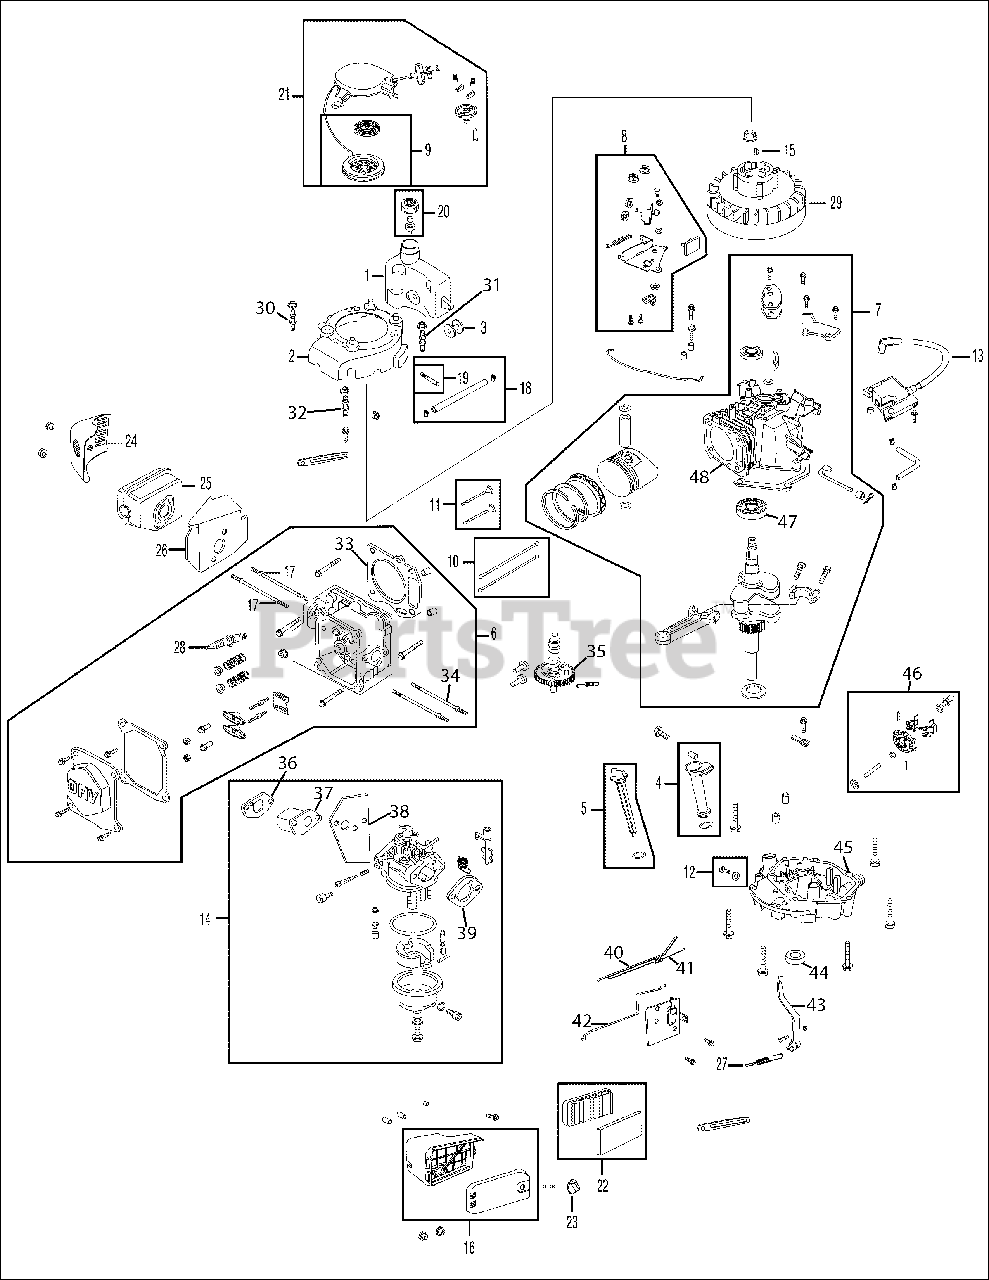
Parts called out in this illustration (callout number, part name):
1	Fuel Tank
2	Flywheel Shroud
3	Rubber Fuel Tank Mounting Washer
4	Oil Filler Tube Assembly
5	Dipstick Assembly
6	Cylinder Head Complete
7	Short Block Assembly
8	Stop Switch and Brake Assembly
9	Recoil Spring and Pulley Assembly
10	Push Rod Kit
11	Valve Kit
12	Oil Drain Plug and Washer Assembly
13	Ignition Coil
14	Carburetor Assembly
15	Flywheel Key
16	Air Cleaner Housing Assembly Complete
17	Muffler Stud Assembly
18	Fuel Line Kit - Inc. hoses, clamps & filter
19	Fuel Filter
20	Fuel Cap Assembly
21	Recoil Starter Assembly
22	Air Cleaner Kit
23	Air Cleaner Thumb Screw
24	Muffler Guard
25	Muffler
26	Muffler Gasket /Heat Shield
27	Governor Return Spring
28	Spark Plug
29	Flywheel
30	Starter/Shroud Stud M6x74
31	Starter/Shroud Stud M6x77
32	Starter/Shroud Stud M6x72.5
33	Cylinder Head Gasket
34	Stud M6 X 92
35	Camshaft Assembly
36	Carburetor Insulator Gasket
37	Carburetor Insulator
38	Carburetor Gasket
39	Carburetor Gasket Plate
40	Throttle Linkage Rod
41	Throttle Linkage Spring
42	Choke Linkage
43	Governor Arm
44	Lower Crankshaft Seal
45	Crankcase Cover
46	Governor Gear/Shaft Assembly
47	Bearing
48	Crankcase Cover Gasket
